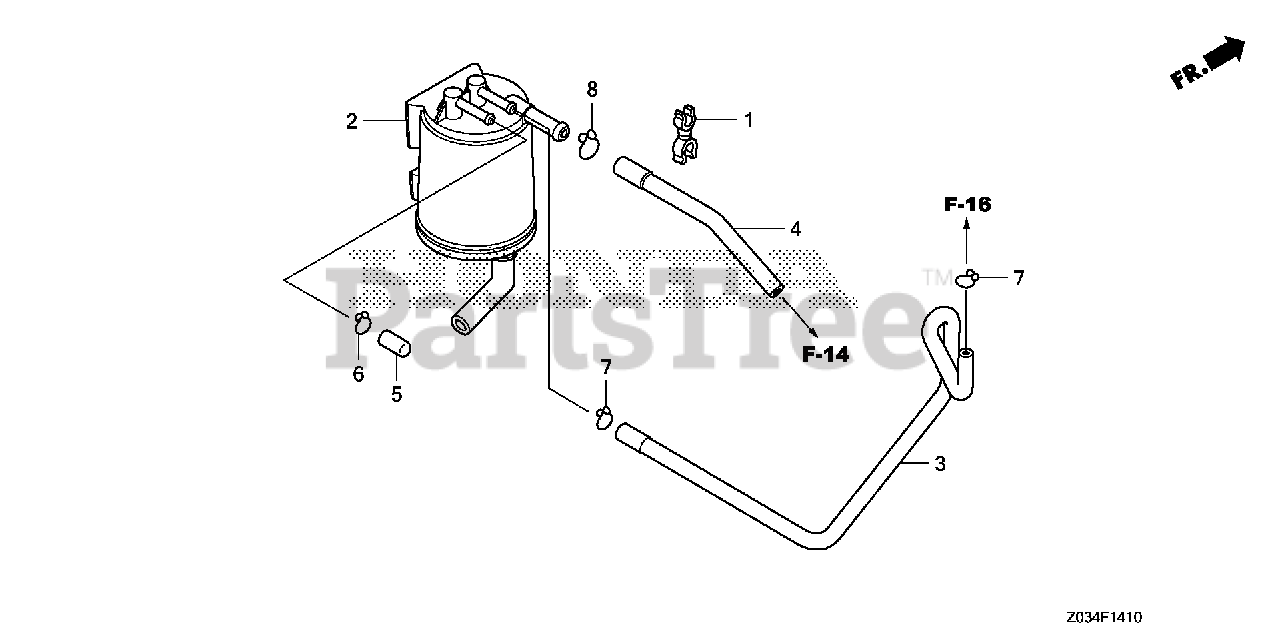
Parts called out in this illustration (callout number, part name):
1	CLAMP, OIL HOSE
2	CANISTER ASSY.
3	TUBE A, CANISTER CHARGE
4	TUBE, CANISTER PURGE
5	CAP, SEALING
6	CLIP, TUBE (B7)
7	CLIP, TUBE (B8)
8	CLIP, TUBE (B12.5)
